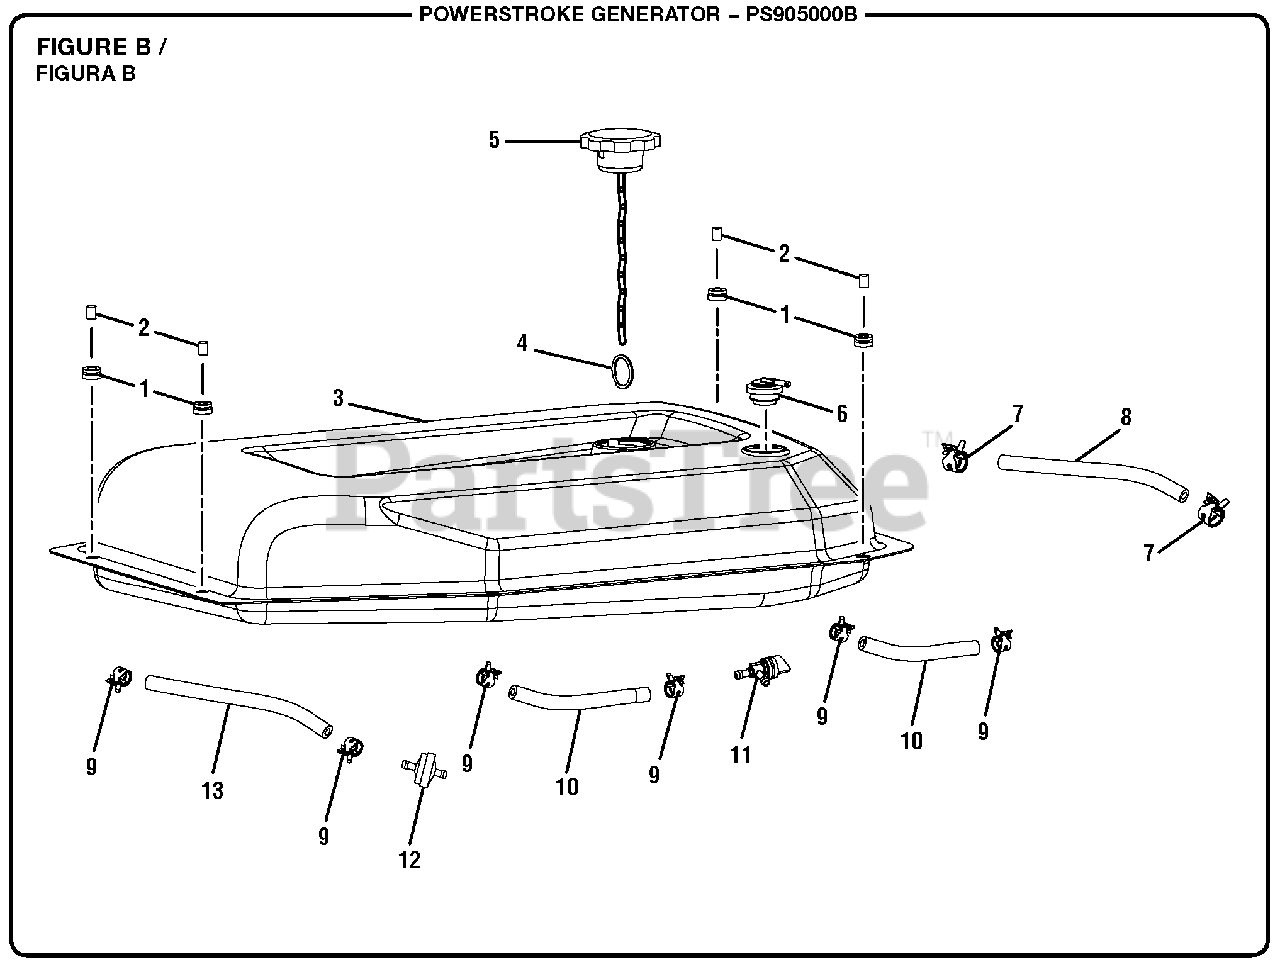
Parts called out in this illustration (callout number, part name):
1	Bushing (Fuel Tank Isolator)
2	Spacer (Fuel Tank Isolator)
3	Fuel Tank
4	Ring Clip
6	Fuel Tank Vapor Vent
7	Fuel Line Clamp (7/16 in.)
8	Vapor Hose
9	Fuel Line Clamp (1/2 in.)
10	Fuel Line (6.4 mm x 72 mm)
11	Fuel Shut Off Valve
12	Fuel Filter
13	Fuel Line (6.4 mm x 72 mm)
